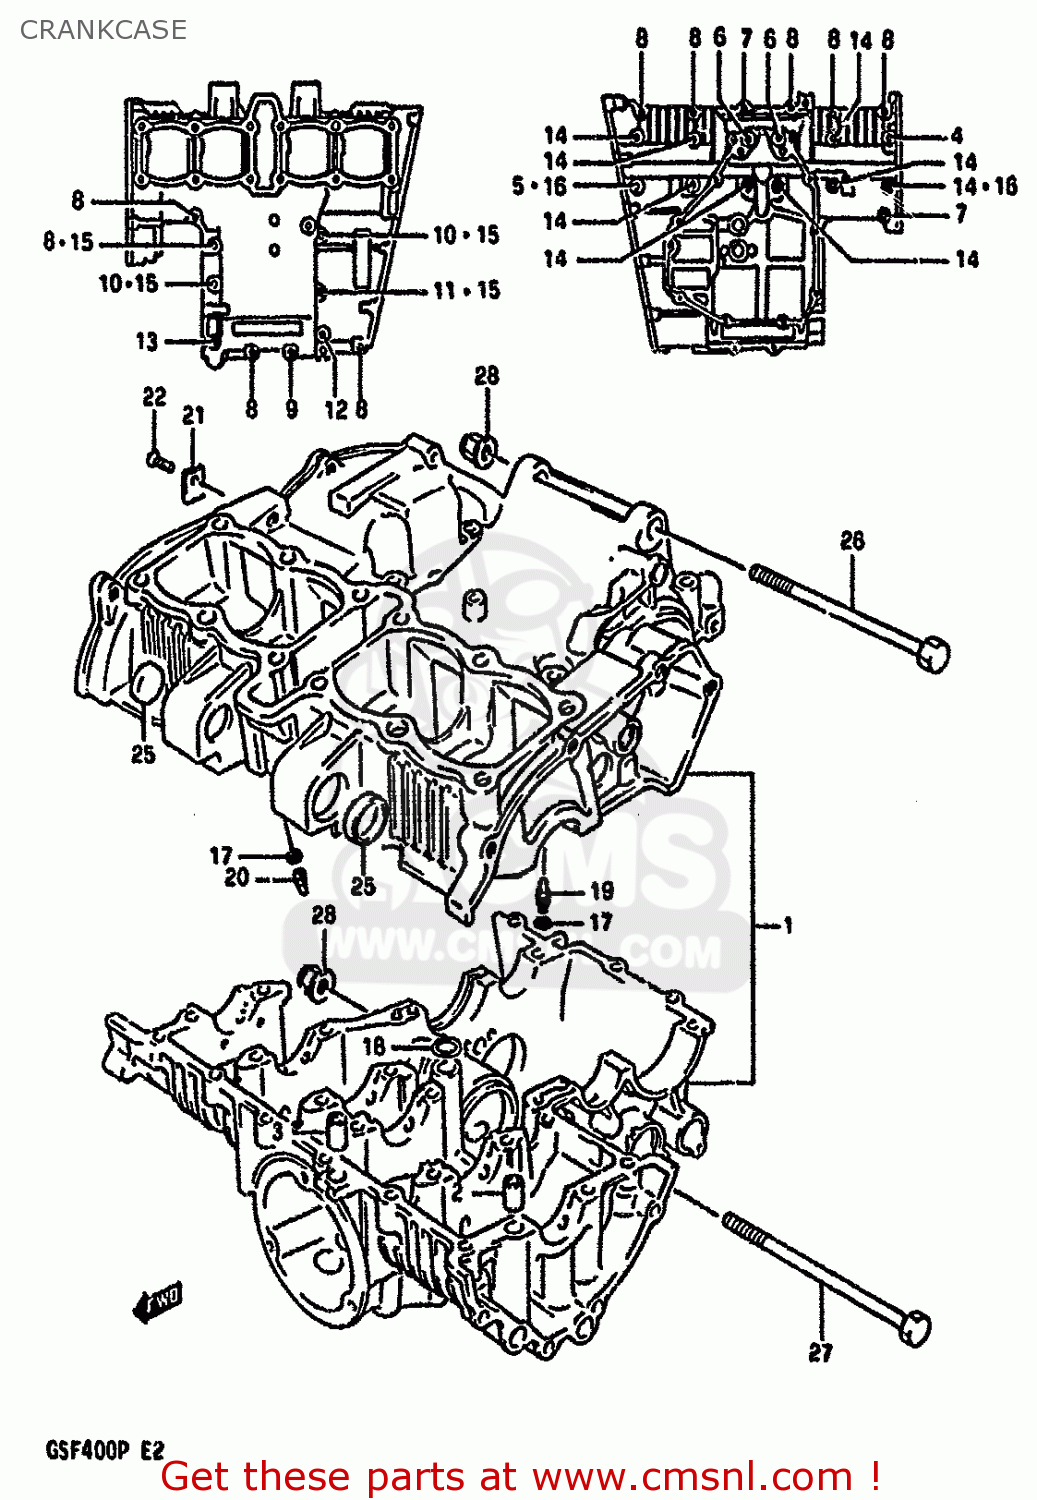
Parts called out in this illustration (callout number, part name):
1	CRANKCASE SET
2	PIN (11X20)(SUS)
3	PIN(10.4X13X22)
4	BOLT
5	BOLT(8X105)
6	BOLT
7	BOLT 6X30
8	BOLT 6X35
9	BOLT (6X45)
10	BOLT 6X55
11	BOLT
12	BOLT
13	BOLT
14	BOLT(8X95)
15	GASKET(6.2X13X1.2) (NAS)
16	GASKET(8.2X14X1) (NAS)
17	O RING(D:1.2,ID:4)
18	O RING(D:1.9,ID:13)
19	JET(8)
20	JET,OIL
21	PLATE,OIL GALLERY PLUG
22	SCREW
23	PLATE,CRANK THRUST
24	PLATE,CRANK THRUST
25	PLUG
26	BOLT 10X135
27	BOLT 10X145
28	NUT (10MM)
